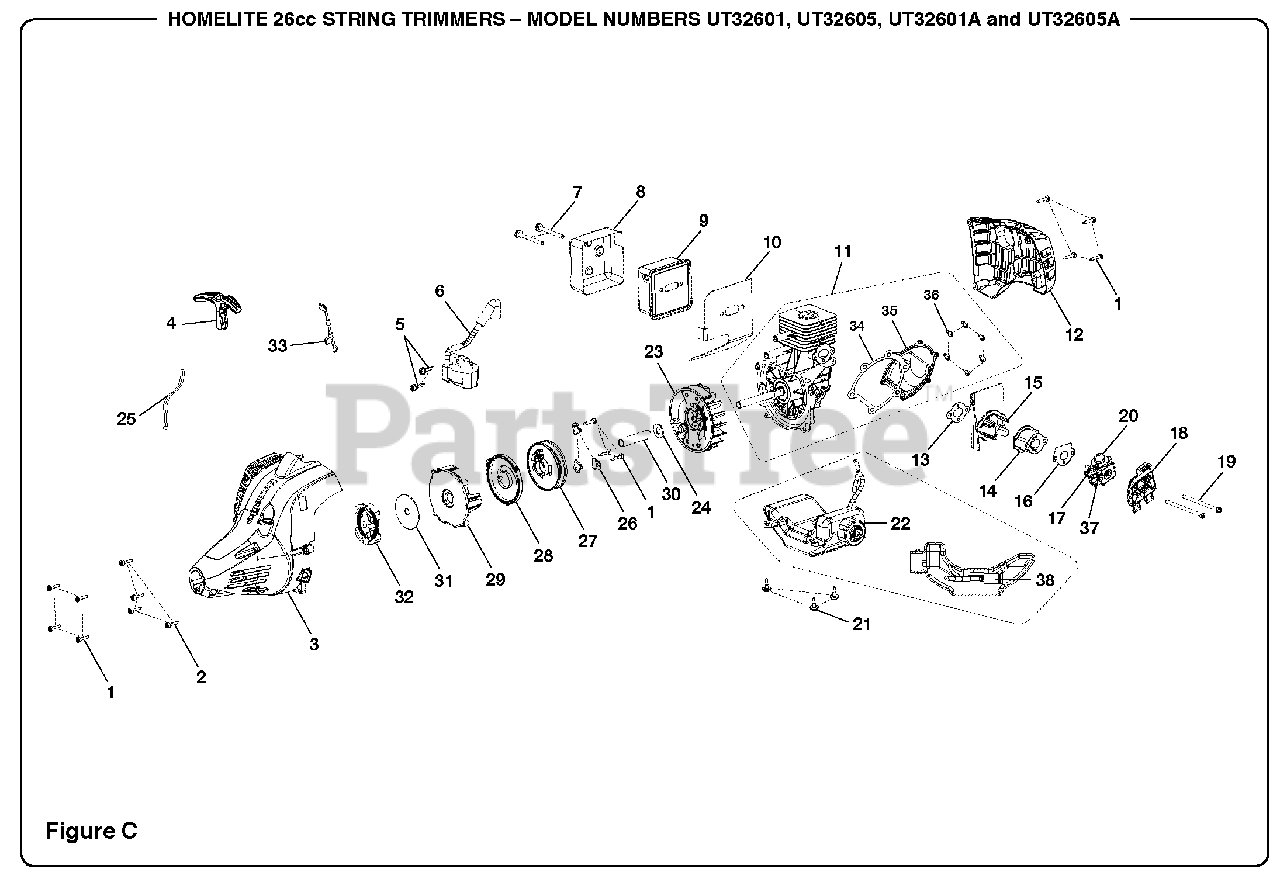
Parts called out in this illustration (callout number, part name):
1	Screw (M4 x 18 mm)
2	Screw (M4 x 16 mm)
3	Front Housing Assembly
4	Pulley Handle
5	Screw (M4 x 19 mm)
6	Ignition Module
7	Screw (10-24 x 2-3/16 in.)
8	Heat Shield
9	Muffler Assembly (Non "A" versions)
10	Muffler Gasket
11	Short Block Assembly
12	Rear Housing
13	Intake Gasket
15	Heat Dam Deflector
16	Carburetor Gasket
17	Carburetor Assembly
18	Air Box Base
19	Screw (M5 x 79 mm)
20	Primer Bulb
21	Screw (M4 x 10 mm Shoulder)
22	Fuel Tank Assembly w/Cap
23	Flywheel Assembly
24	Washer
25	Starter Rope (42 in.)
26	Pulley Retainer
27	Starter Pulley Assembly
28	Spring & Container Assembly
29	Starter Housing
30	Spacer Tube
31	Clutch Washer
32	Clutch Assembly
33	Lead Assembly
34	Gasket
35	Crankcase Cover
36	Screw (M4 x 12 mm)
37	Choke Lever
38	Fuel Filter
